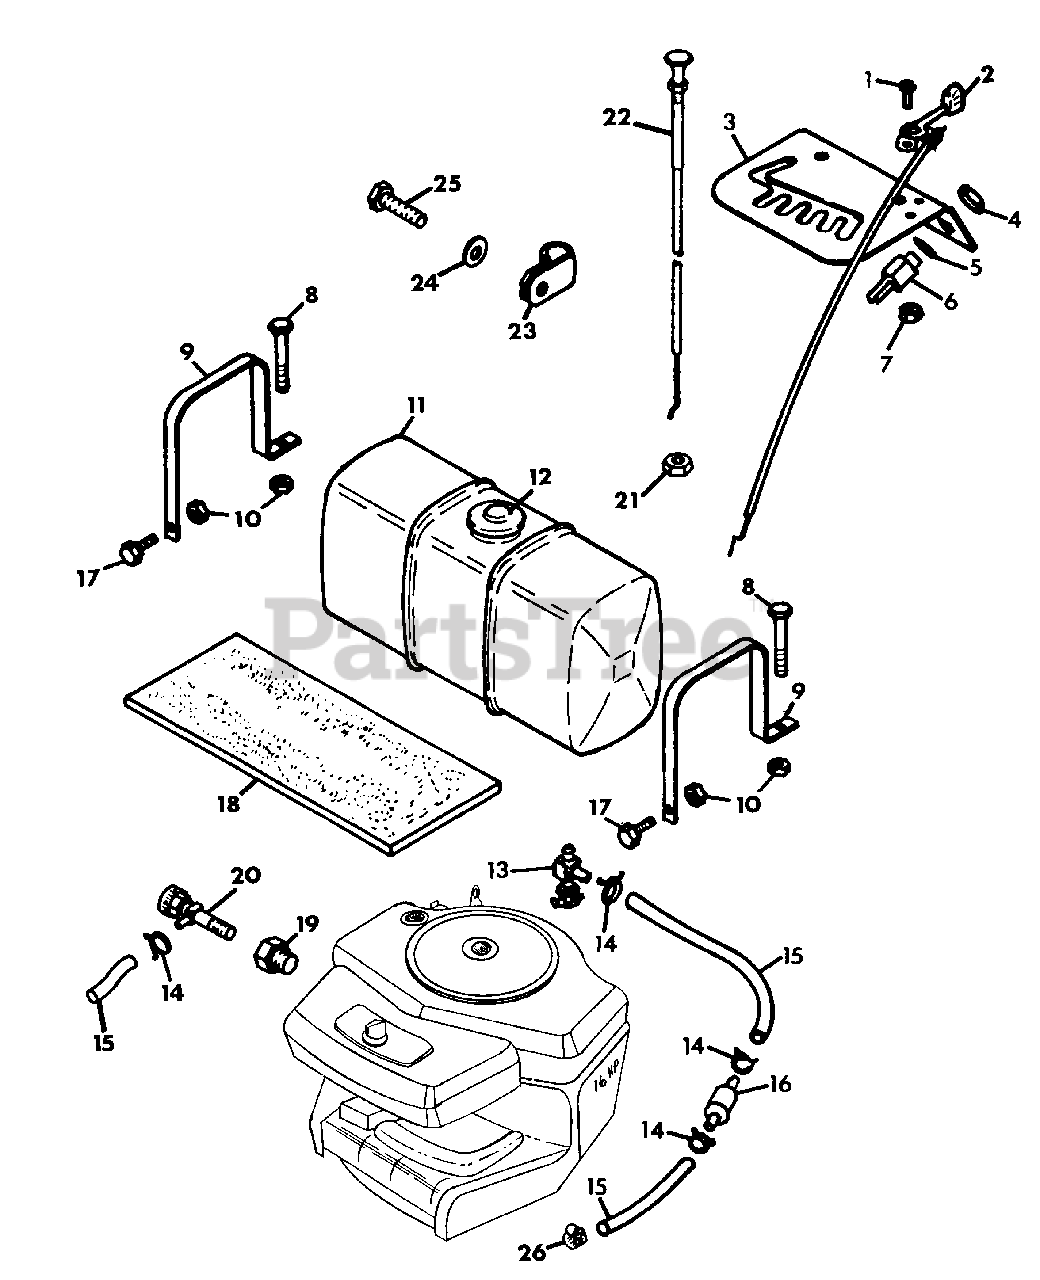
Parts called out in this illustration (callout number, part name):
1	SCREW, MACH. 10-24X.50
2	LEVER, CONTROL
3	PLATE, INSTRUCTION
4	NUT, JAM 9/16-24
5	WASHER, LOCK
6	SWITCH, IGNITION
7	NUT, LOCK 10-24
8	BOLT, HEX 1/4-20X1.75
9	STRAP, FUEL TANK
10	NUT, LOCK 1/4-20
11	TANK, FUEL (12 QTS.)
12	CAP, FUEL TANK
13	VALVE AND STRAINER
14	CLAMP, FUEL HOSE
15	HOSE, FUEL
16	FILTER, FUEL
17	BOLT, HEX 1/4-20X.625
18	PAD, FUEL TANK
19	ADAPTOR, OIL DRAIN
20	COCK, OIL DRAIN
21	NUT, JAM 3/8-24 HEX HEAD
22	CONTROL, CHOKE
23	CLAMP
24	WASHER, FLAT .281X.625X.065
25	BOLT, HEX 1/4-20X1.00
26	CLAMP, HOSE
